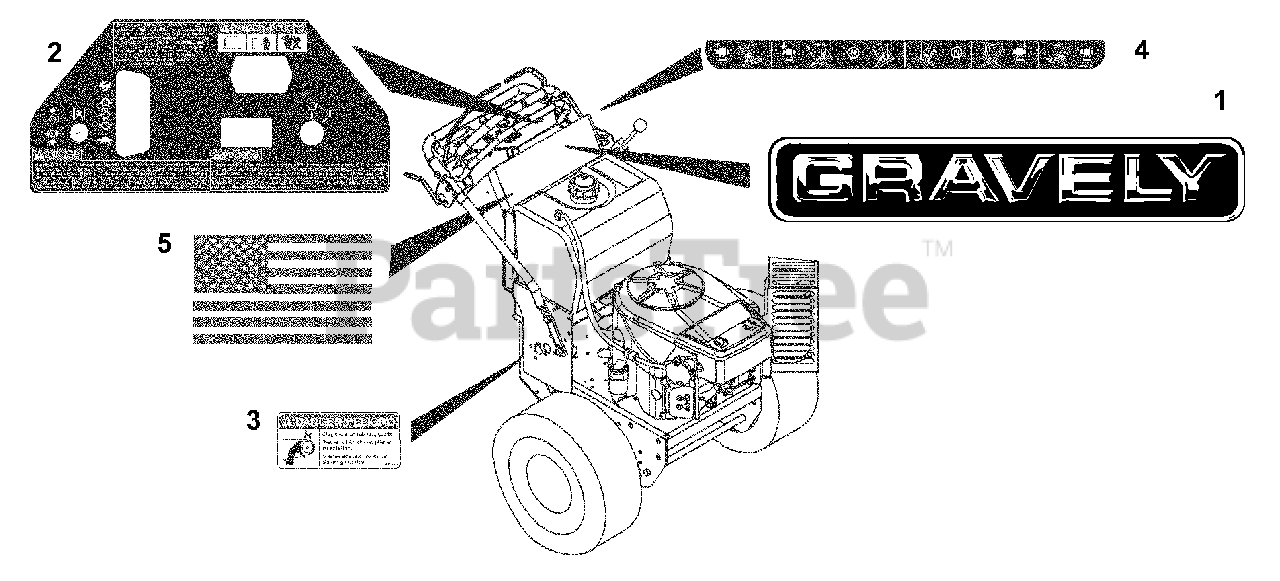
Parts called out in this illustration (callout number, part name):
1	Decal- 15" Gravely Logo
2	Decal, Control HR15- Pro Steer
3	Decal, Danger-Belt Rotating
4	Decal, Steer Levers-Hydro-Pro Steer
5	Decal, American Flag
